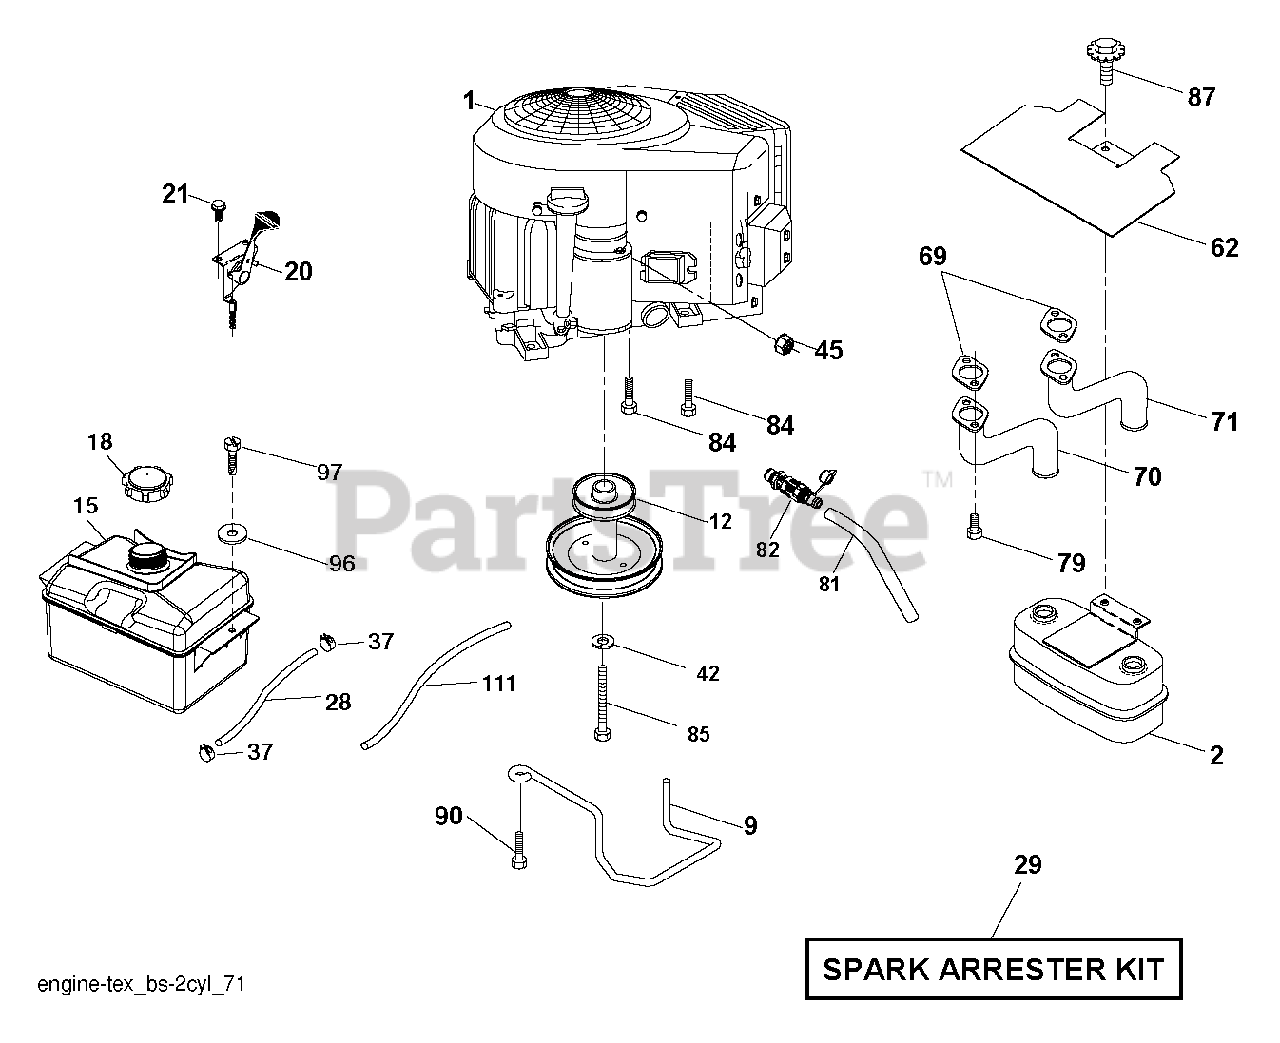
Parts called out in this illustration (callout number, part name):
2	MUFFLER.TWIN.CYL.LOW.TONE
9	Belt Keeper, 4 25"2 Blt 431
12	Engine Pulley
15	TANK.ASM.FRT.2.5 GAL.W/CAP.EPA
18	Fuel Cap, 2-Way Vent
20	CONTROL.TH/CK.COBRA.B&S.TWN.
21	SCREW.#10 X 0.750.BOS THREAD
28	LINE.FUEL.20"FRONT.EMI
29	ARRESTER SPARK (OPTIONAL)
37	HOSE CLAMP
42	LOCKWASHER
45	NUT
62	SHIELD.HEAT.MUFFLER
69	GASKET.MUFFLER
70	Exhaust Tube, LH.Bs/Twin
71	Exhaust Tube, RH B&S Twin Intek
79	SCREW.SOCKET.HEAD.5/16-18
81	TUBE, DRAIN OIL ASM.
82	VALUE.OIL.DRAIN
84	SCREW.3/8-16
85	BOLT HEX 7/16-20X4-1/4"
87	BOLT 5/1618UNC X 3/4 W/ SEMS
90	SCREW 3/8-16X1
96	WASHER
97	SCREW HEXWSHR 1/4-20X3/4
111	RP PURGE LINE
